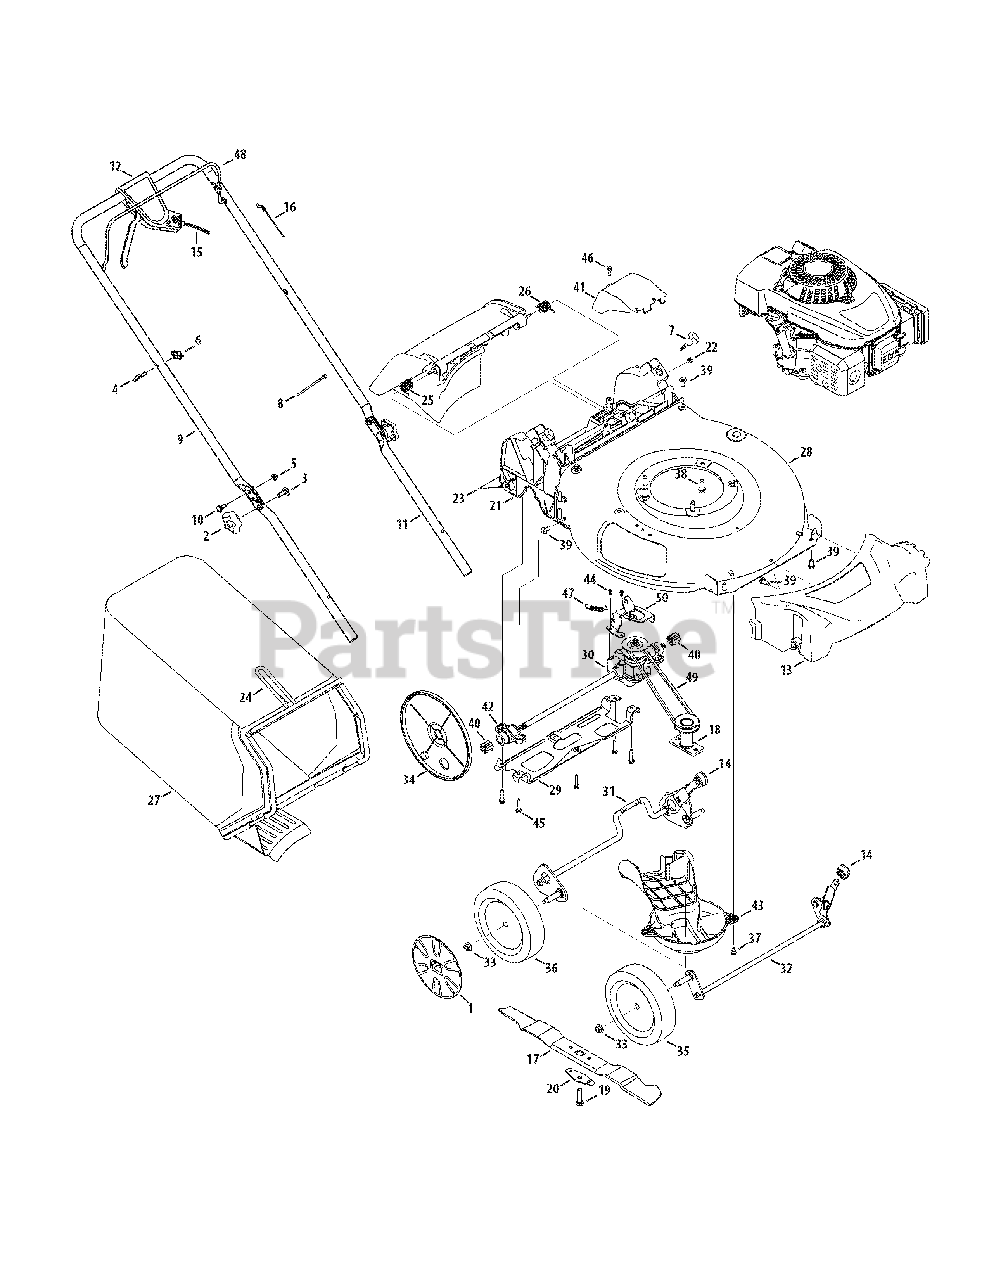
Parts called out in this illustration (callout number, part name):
1	Hubcap
2	Wing Knob
3	Carriage Screw ,5/16-18
4	Rope Guide
5	Nut, Flange Lock, 1/4-20
7	Wing Knob
8	Cable Tie
10	Shdr. Screw, .375 x .126 x 1/4-20
11	Lower Handle
12	Control Lever Assembly
13	Front Cover
14	Adjustment Lever Knob
15	Variable Speed Cable
16	Control Cable
17	Mulching Blade
18	Blade Adapter
19	Screw, 3/8-24 x 1.50
20	Blade Bell Support
21	Rear Discharge Door Assembly
22	Nut, Sq., 1/4-20
23	Trail Shield
24	Grass Catcher Frame
25	Torsion Spring - RH
26	Torsion Spring - LH
27	Grass Bag
29	Rear Support Bracket
30	Transmission Assembly
31	Rear Axle Assembly
32	Front Axle Assembly
33	Flange Lock Nut, 3/8-16
34	Wheel Dust Cover
35	Front Wheel, 8 x2
36	Rear Wheel, 8 x 2
37	Scr., Shldr., 1/4-20 x .50
38	Screw, tt, 3/8-16 x 1.00
39	Screw, 5/16-14 x .750
40	Spur Gear, 10T
41	Transmission Cover
42	Bearing Assembly
43	Engine Baffle
44	Screw, Hex Washer, .159 x .43
45	Screw, 1/4-15 x 1.25
46	Screw, 1/4-15 x .750
47	Exten. Spring, 2.675
48	Blade Control
49	V-Belt
50	Transmission Bracket
